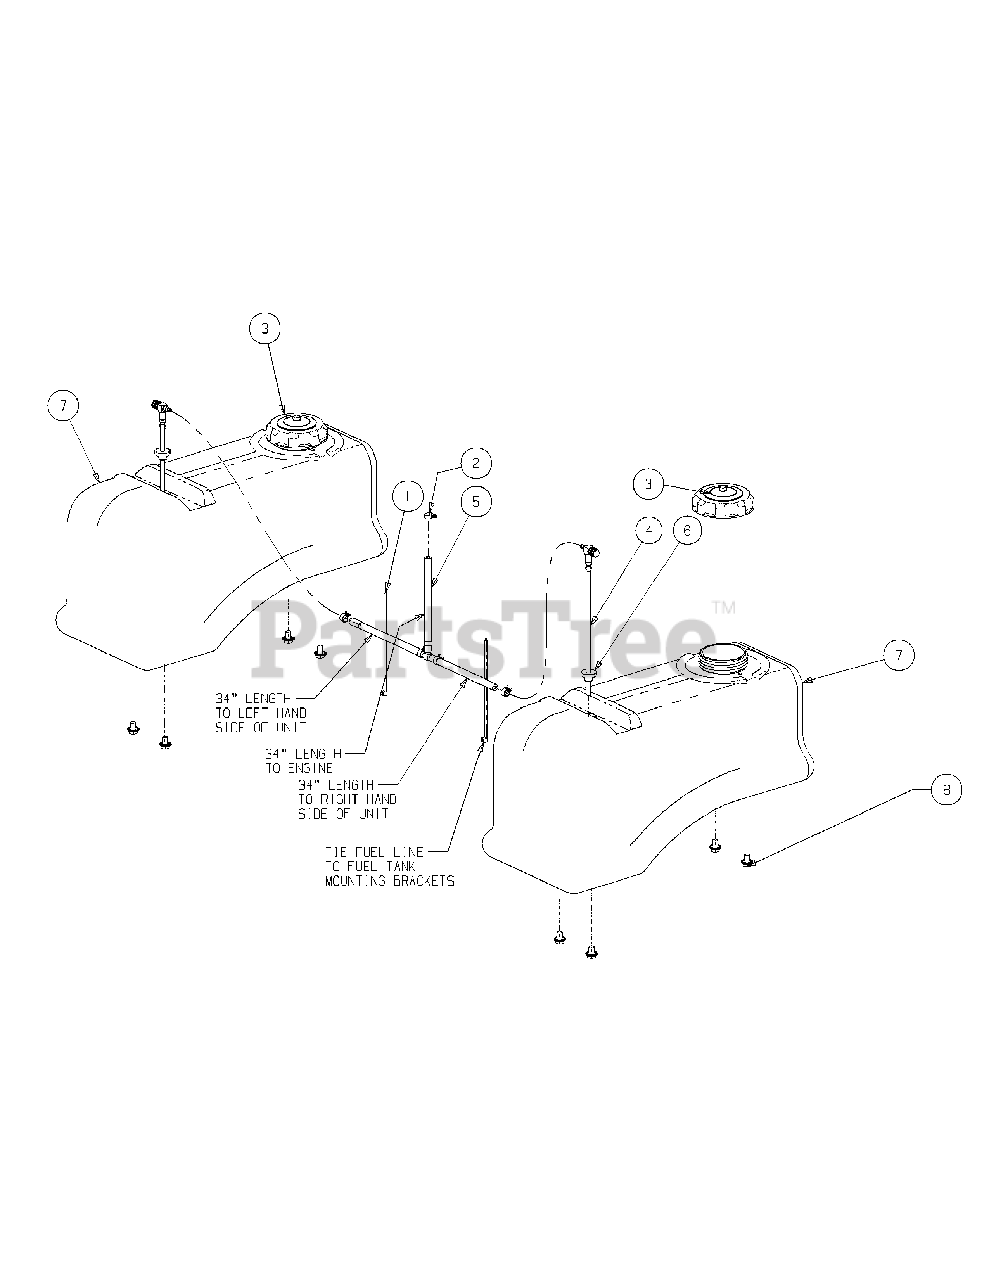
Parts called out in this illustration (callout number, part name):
1	Cable Tie
2	Hose Clamp, SAE #4: 1/4-5/8, SS
3	Fuel Cap, 3.5
4	Fuel Fitting
5	Fuel Hose Assembly includes:
5	Hose, 1/4" Fuel Line
5	Clamp, Union
5	Tee Fitting, Fuel
6	Grommet, Fuel Tank
7	Fuel Tank
8	Hex Cap Screw, 3/8-16 x .50 Flange Whiz
